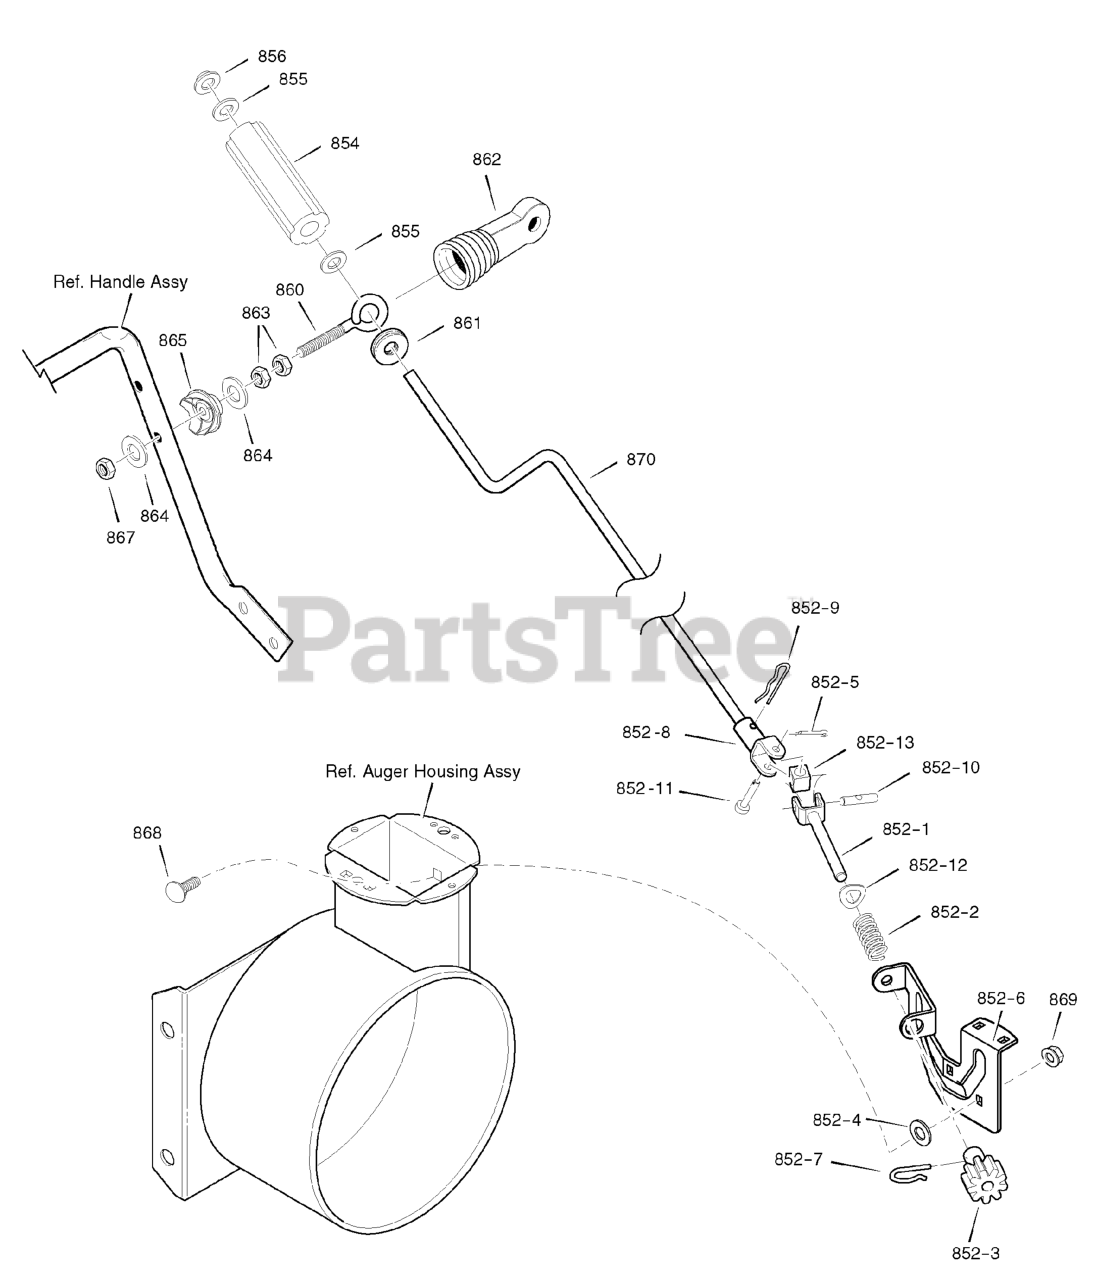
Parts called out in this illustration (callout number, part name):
852-1	ASSEMBLY, YOKE & ROD
852-3	GEAR, CHUTE ROTATION 9T
852-4	WASHER, .470- 1.00.25 FLT
852-5	PIN, COTTER
852-6	BRACKET, CHUTE GEAR
852-7	PIN, HAIR
852-8	ASSEMBLY, YOKE ADAPTER YZ
852-9	PIN, HAIR
852-10	PIN, UNIVERSAL JOINT
852-11	PIN, CLEVIS
852-13	HOUSING, UNIVERSAL
854	KNOB, SLEEVE
855	FLATWASHER
856	NUT, PUSH ON 3/8"
860	EYE BOLT 3/8-16 X 6.00
861	GROMMET, EYE BOLT
862	BOOT, EYE BOLT
863	NUT, 3/8-16 HEXJAM
864	WASHER, Flat, 13/32
865	ADAPTER, BOOT
867	NUT, 3/8-16 HEXNYL
868	BOLT, CARRIAGE 1/4-20 X 1.00
869	NUT, 1/4-20
870	CRANK, ASSEMBLY CHUTE
